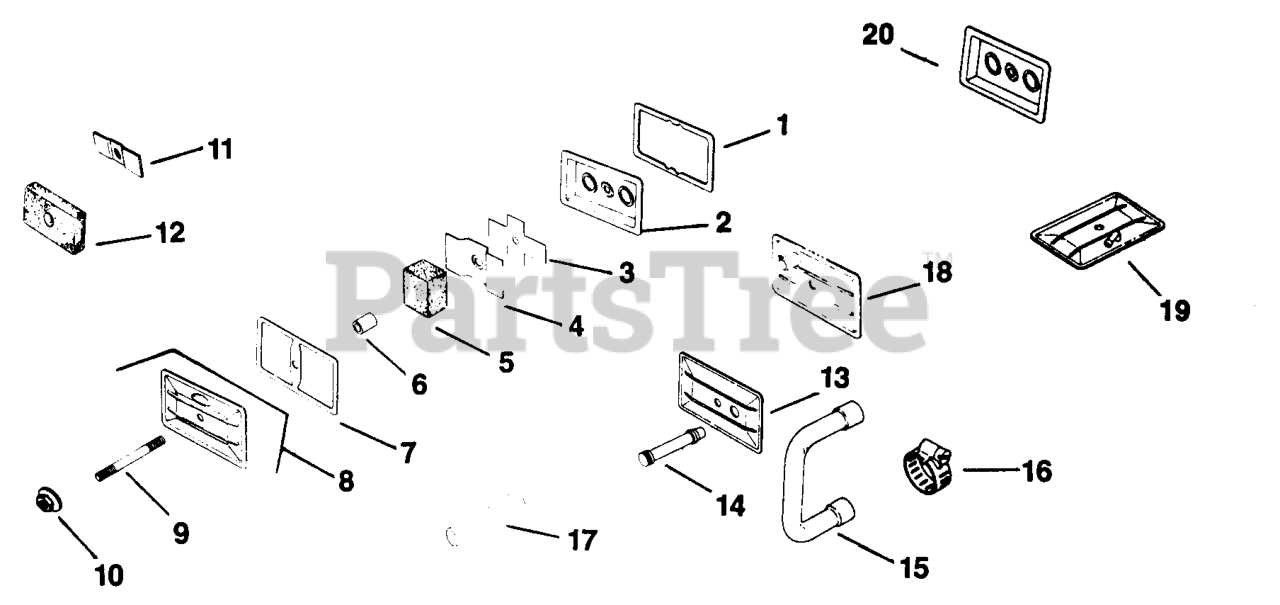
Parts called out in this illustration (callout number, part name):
1	GASKET, VALVE COVER
2	PLATE, BREATHER
3	REED, BREATHER - Use 47 402 01-S Breather Reed
4	BAFFLE, BREATHER
5	FILTER, BREATHER
6	SEAL, BREATHER
7	GASKET, VALVE COVER
8	KIT, COVER
9	STUD, 1/4-20x3-1/4" - DISCONTINUED
